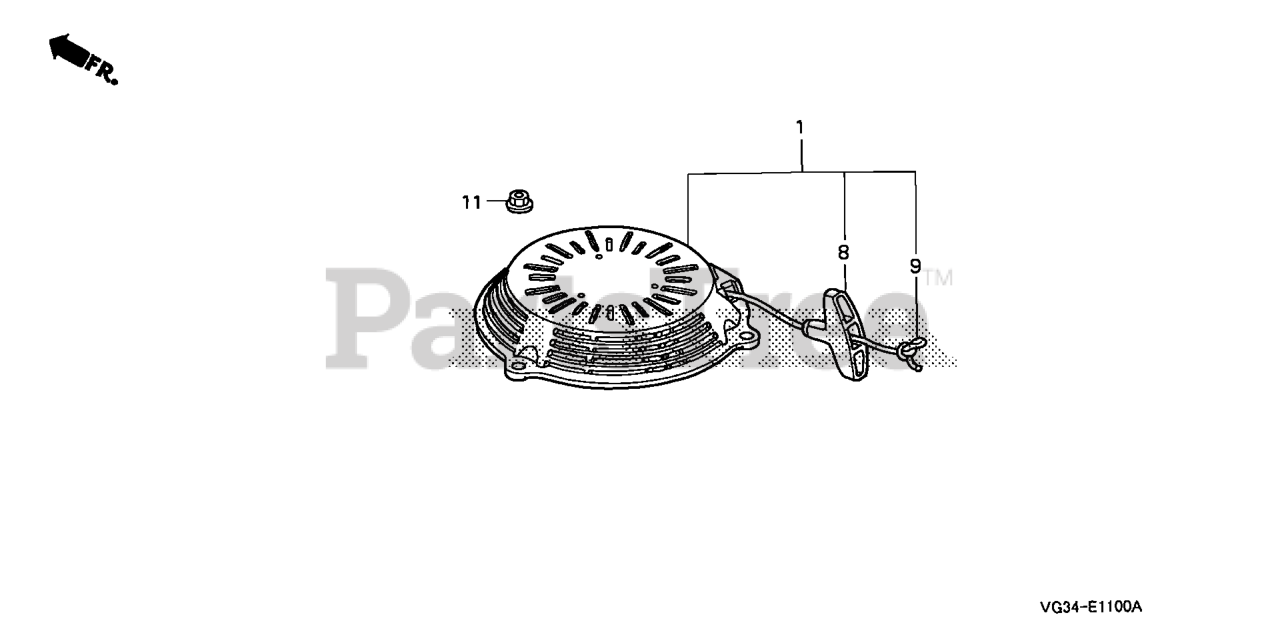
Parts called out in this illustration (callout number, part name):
1	STARTER ASSY., RECOIL *R280* (LONG ROPE) (POWER RED)
8	KNOB, RECOIL STARTER
9	ROPE, RECOIL STARTER (LONG TYPE)
11	NUT, FLANGE (6MM)
